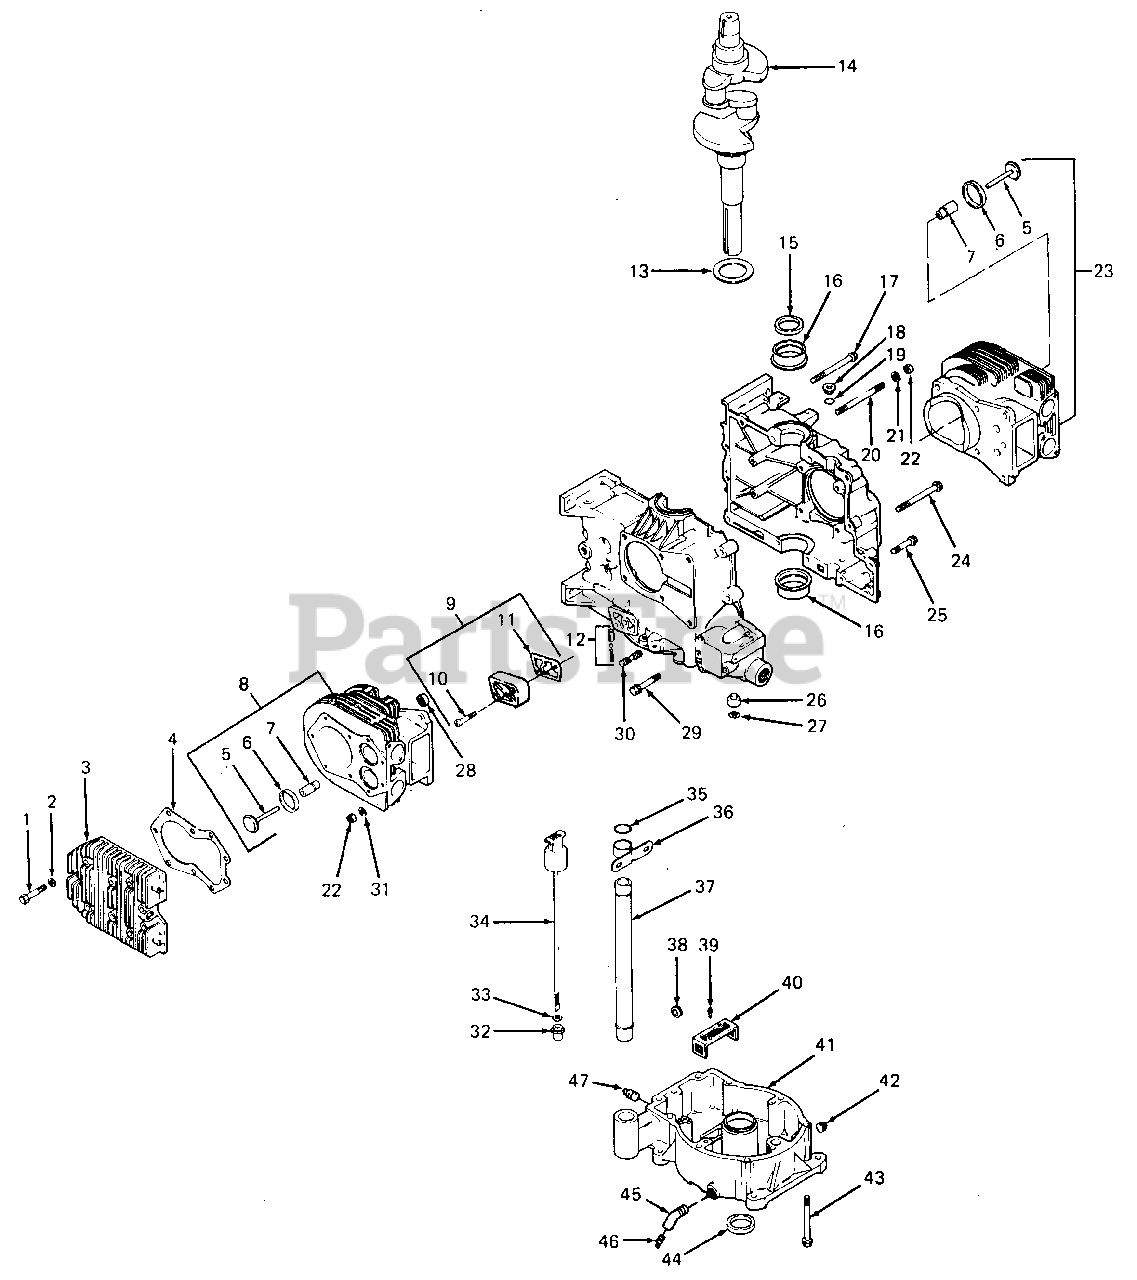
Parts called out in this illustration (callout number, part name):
1	Screw, Hex Hd, 5/16-18 X 1-1/2
2	Washer, Plain, 5/16
3	Head, Cylinder
4	Gasket, Cylinder Head
5	Valve, Exhaust
6	Insert, Valve Seat
7	Valve, Guide
8	Kit, #1 Cylinder Barrel
9	Oil Filter Kit, Non-Filter Cover
10	Screw, Hex Socket Hd, 5/16-18 X 1-1/4
11	Gasket, Oil Filter
12	Oil Relief Kit
13	Washer, Thrust, .119/.122
14	Crankshaft, 3-5/32 X 1 in., Tapped PTO
15	Seal, Front Oil
16	Bearing, Sleeve, Std
17	Screw, Hex Flange, 5/16-18 X 3-1/2
18	Plug, 3/4 in. OD
20	Stud, 5/16-18 X 4-1/8
21	Washer, Plain
22	Nut, Hex, 5/16-18
23	Kit, #2 Cylinder Barrel
24	Screw, Hex Flange, 3/8-16 X 3-5/8
25	Screw, Hex Flange, 5/16-18 X 1-1/2
26	Shaft, Governor
27	Ring, Retaining
28	Bushing, Locating
29	Screw, Hex Flange, 5/16-18 X 2
30	Stud, Step, 5/16-18 X 3/4, 3/8-16 X 5/8, 2 in. Lg
31	Washer, Flat, 5/16
32	Seal, Rubber
33	Washer, Plain, 5/16
34	Dipstick, 13-1/2 in. Blade
36	Bracket, Oil Tube Support
37	Tube, Oil Fill, 11-7/8
38	Plug, Hex Ctsk, 3/4 NPTF
39	Screw, Hex Wash Hd, 10-32 X 7/16
40	Filter, Oil Pickup
41	Pan, Oil
42	Plug, Sq Solid Hd, 3/8 NPTF
43	Screw, Hex Wash Hd, 5/16-18 X 3-1/4
44	Seal, Rear Oil
45	Pipe, Oil Drain
46	Plug, Pipe, H-Hd Auto, 1/4-18 ZNP
47	Plug, Hex Ctsk, 1/4 NPTF
